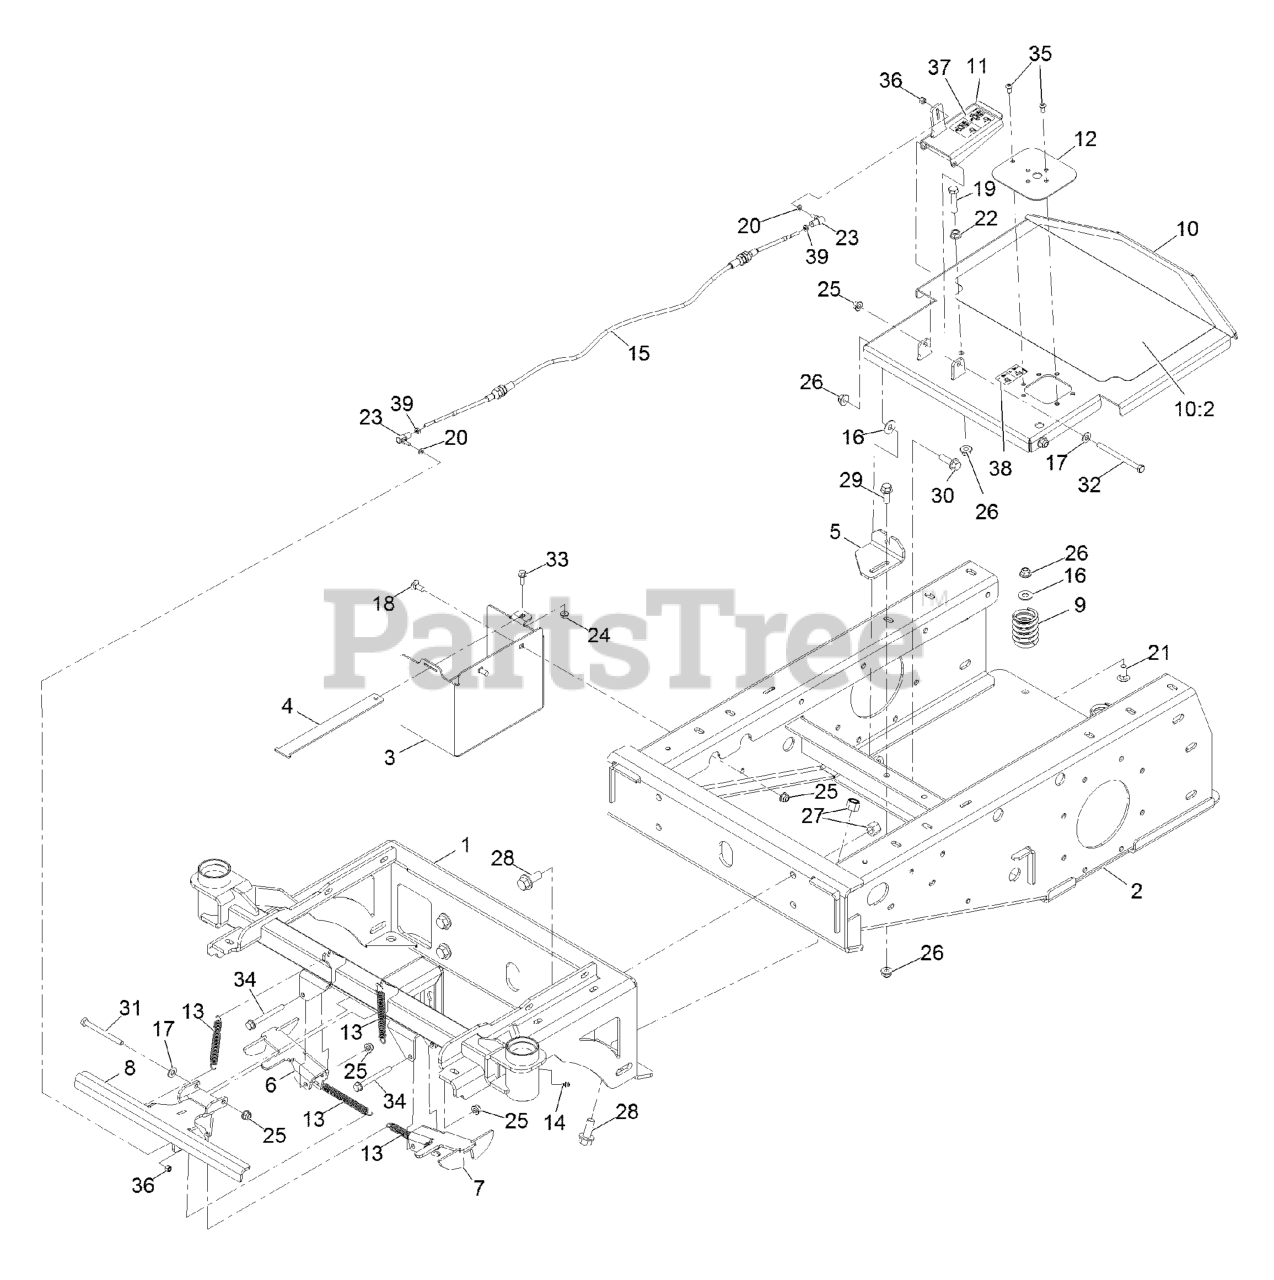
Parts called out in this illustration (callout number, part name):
1	Frame-Front
2	FRAME-REAR
3	Box-Battery
4	STRAP-BATTERY
5	Bracket, Lower Cable
6	Wing-Capture, Rt
7	Wing-Capture, Lt
8	Capture-Lcs
9	SPRING-COMPRESSION
10	Plate-Foot
10:2	PAD-GRIP
11	Pedal-Foot
12	Panel, Foot Switch
13	SPRING-EXTENSION
14	FITTING-GREASE, ZERK
15	CABLE-CASTER, LOCKING
16	WASHER-FLAT
18	SCREW-CARR
19	Screw-HH
20	WASHER-FLAT
21	SCREW-CARR
22	Nut-Hex Flange
23	BALL JOINT-SS
24	Nut-Hex Flange
25	Nut-Hex Flange
26	Nut-Hex Flange
27	Nut,1/2-13,NYL INS,ST/ST,18-8
28	SCREW-HHF
29	SCREW-HHF
30	SCREW-HHF
31	SCREW-HH
32	Screw-HH
33	Screw-HHF
34	SCREW-HHF
35	Screw-HSBH
36	Nut,NYL Lock,#10-32,ST/ST 18-8
37	Decal-Lock, Caster
38	Decal-Spray Foot Button
39	Nut,Hex Jam Mch Scr,10-32,Sst
